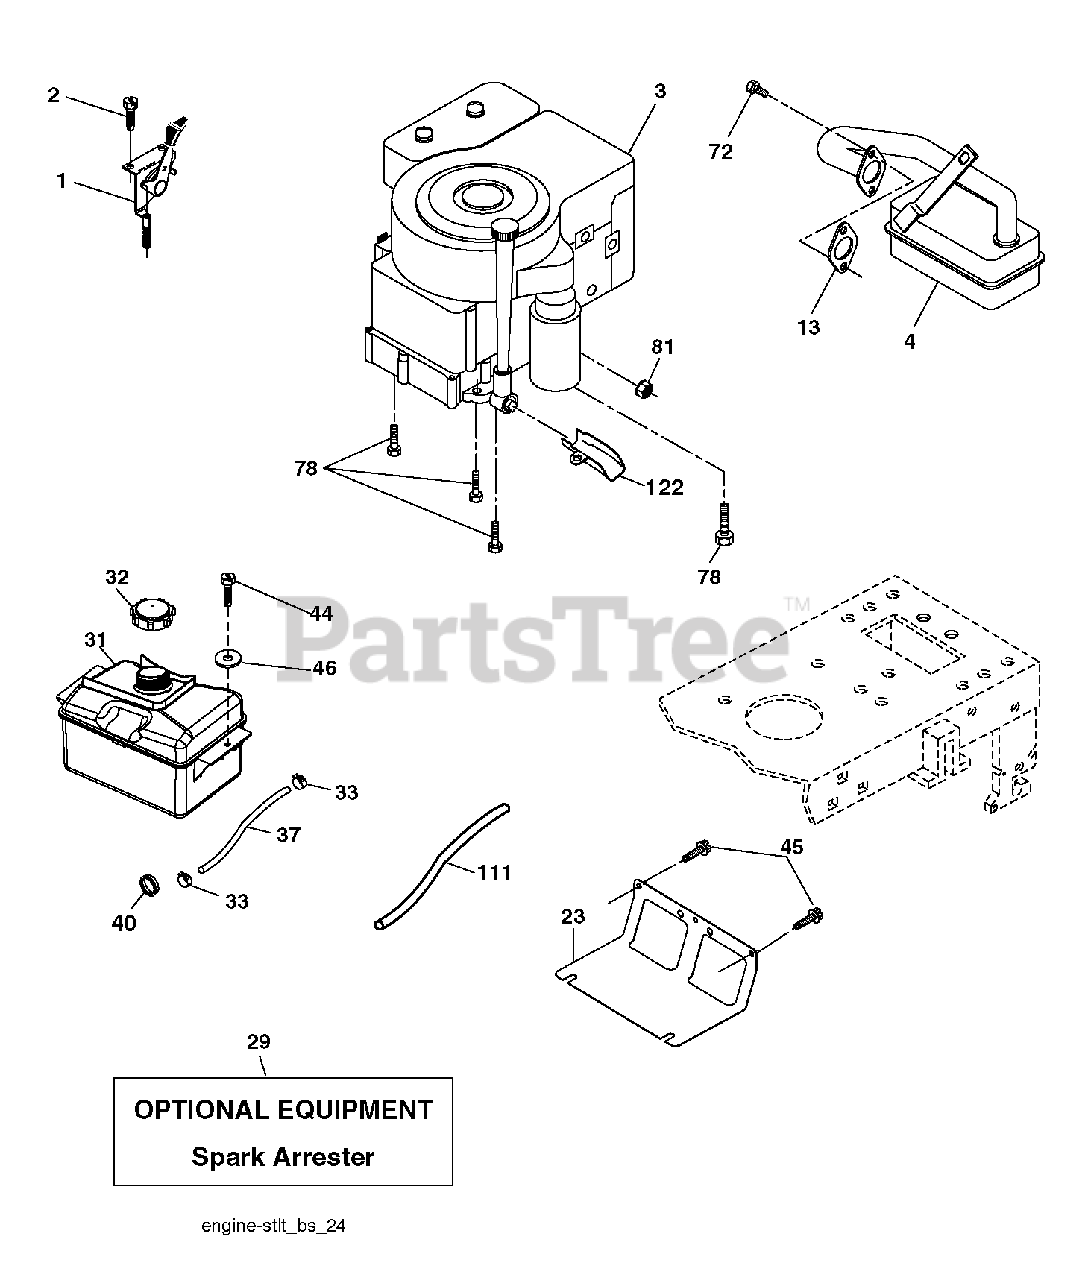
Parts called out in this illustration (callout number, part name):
1	CONTROL.THROTTLE/CHOKE.BLACK
2	SCREW
4	MUFFLER.LT.BRIGGS.14HP.IC/OHV
23	SHIELD.BROWNING.DBR.GUARD
29	KIT.SPARK ARRESTOR(392390 B&S)
31	TANK.ASM.1.5GAL.FRT.W/CAP.EPA
32	CAP.2.25'.VENTED.RATCHET.EPA
33	HOSE CLAMP
37	LINE.FUEL.20"FRONT.EMI
40	GROMMET T
44	SCREW HEXWSHR 1/4-20X3/4
45	SCREW, 3/8-16X3/4
46	WASHER
72	SCREW.SOCKET HD.5/16-1
78	SCREW.3/8-16
81	NUT
111	RP PURGE LINE
122	EXTENSION DRAIN OIL
